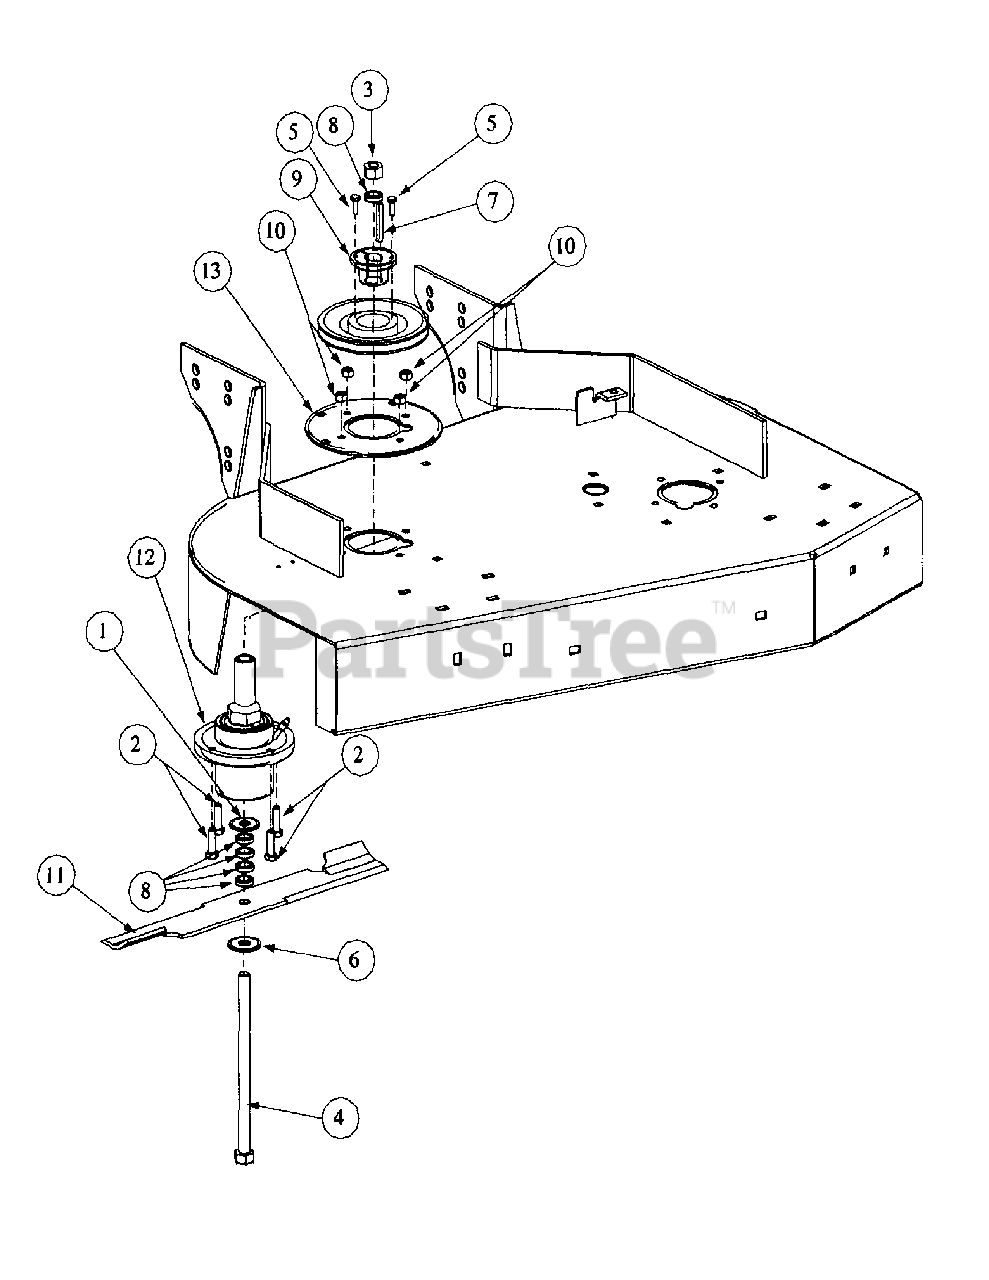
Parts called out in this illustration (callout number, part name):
1	Flat Washer, 1-1/2 x 5/8 x .05
2	Hex Cap Screw, 3/8-16 x 1-1/4
3	Hex Nut, 5/8-11
4	Hex Cap Screw, 5/8-11 x 9-1/2
5	Hex Cap Screw, 1/4-20, .75
6	Flat Washer, 5/8 Zinc
7	Key Stick, 1/4 x 1/4 x 2
8	Blade Spacer, 5/8 ID, 1/4 Thick
9	Bushing
10	Lock Nut, 3/8-16
11	Blade 18"
12	Spindle Assembly
13	Plate, Spindle Backing
